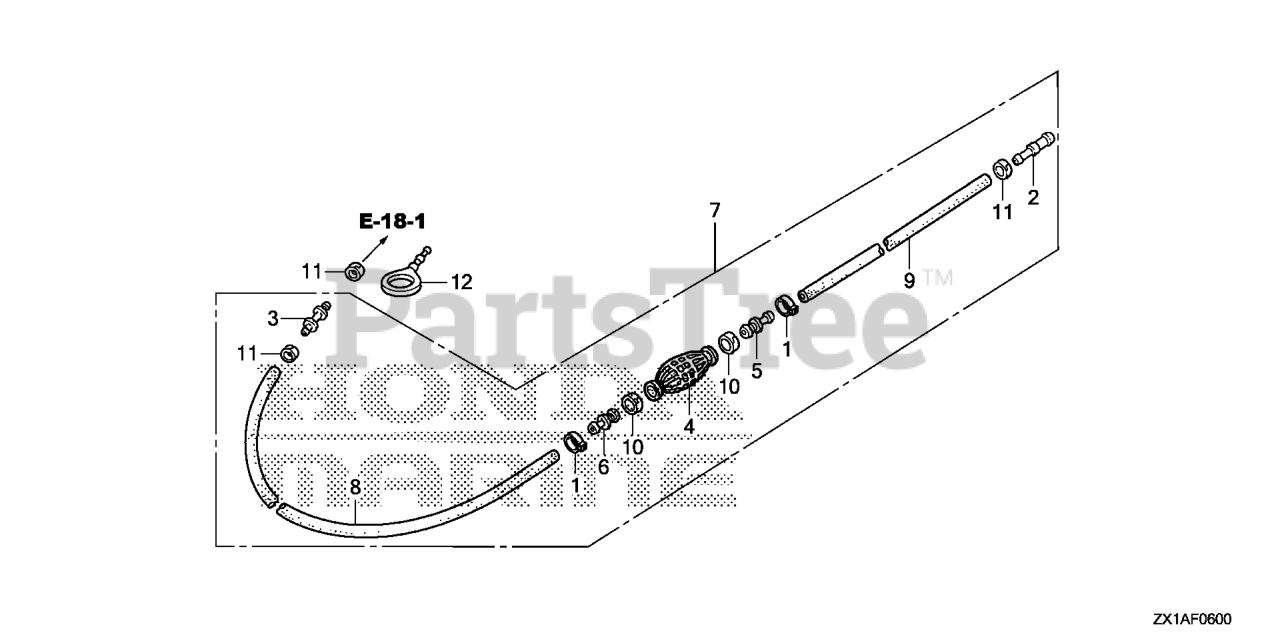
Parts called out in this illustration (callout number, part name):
1	CLAMP, FUEL TUBE (14.0) (CONNECTOR TYPE)
2	JOINT, FUEL TUBE (JOINT TYPE)
3	JOINT, FUEL TUBE
4	BULB, PRIMER
5	VALVE, IN.
6	VALVE, OUTLET
7	TUBE, FUEL TANK
7	TUBE ASSY., FUEL TANK (JOINT TYPE)(FKM)
8	TUBE, FUEL LONG (75)
8	TUBE, FUEL LONG (7.3X2000)
9	TUBE, FUEL SHORT
9	TUBE (75)
10	BAND, TUBE CLIP (20MM)
11	BAND, TUBE CLIP (12.5MM)
12	PLUG, FUEL TUBE
